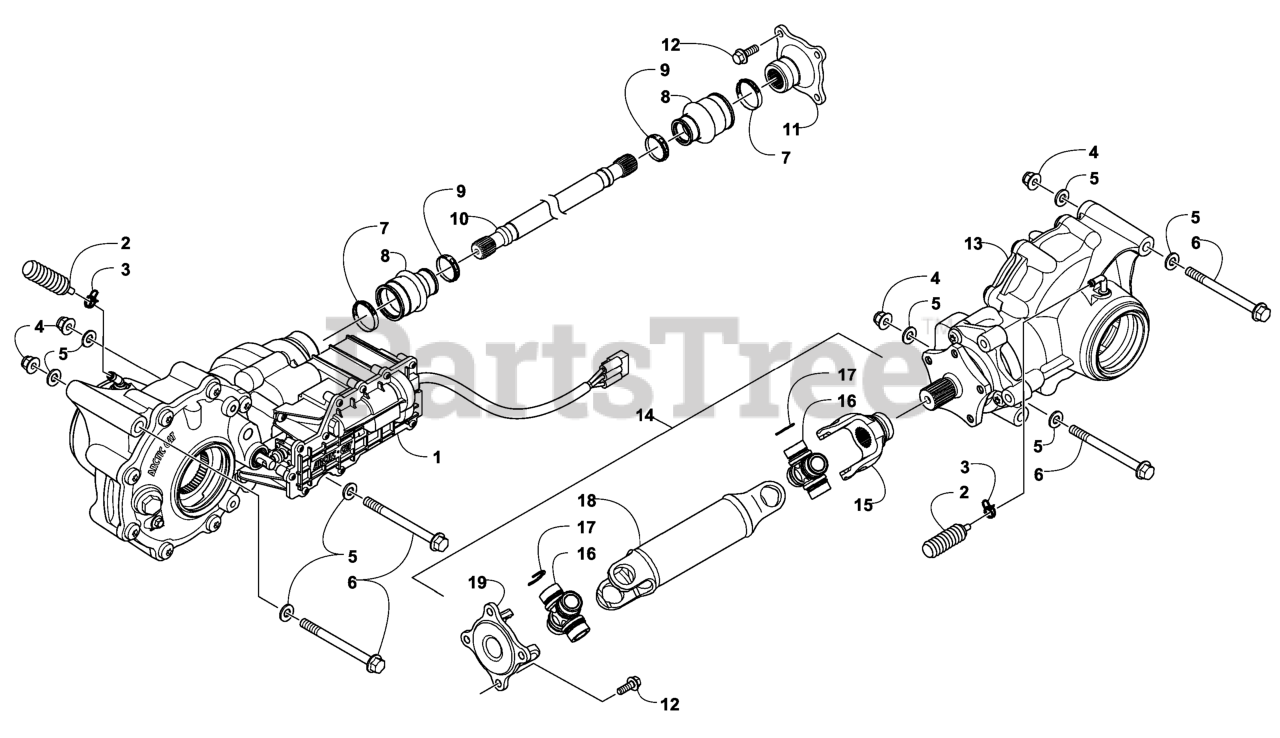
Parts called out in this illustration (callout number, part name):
1	GEARCASE-FRONT
2	BLADDER-CASE
3	CLAMP-HOSE, DOUBLE WIRE
5	WASHER-FLAT
6	SCREW-HFH
8	BOOT-COUPLER
10	SHAFT-PROPELLER, FRONT
11	FLANGE-OUTPUT
12	SCREW-HFH
13	GEARCASE-REAR
14	DRIVESHAFT-REAR
15	YOKE-SLIP
16	CROSS-UNIVERSAL
17	RETAINER-CROSS
18	DRIVESHAFT-REAR
19	YOKE-FLANGE
